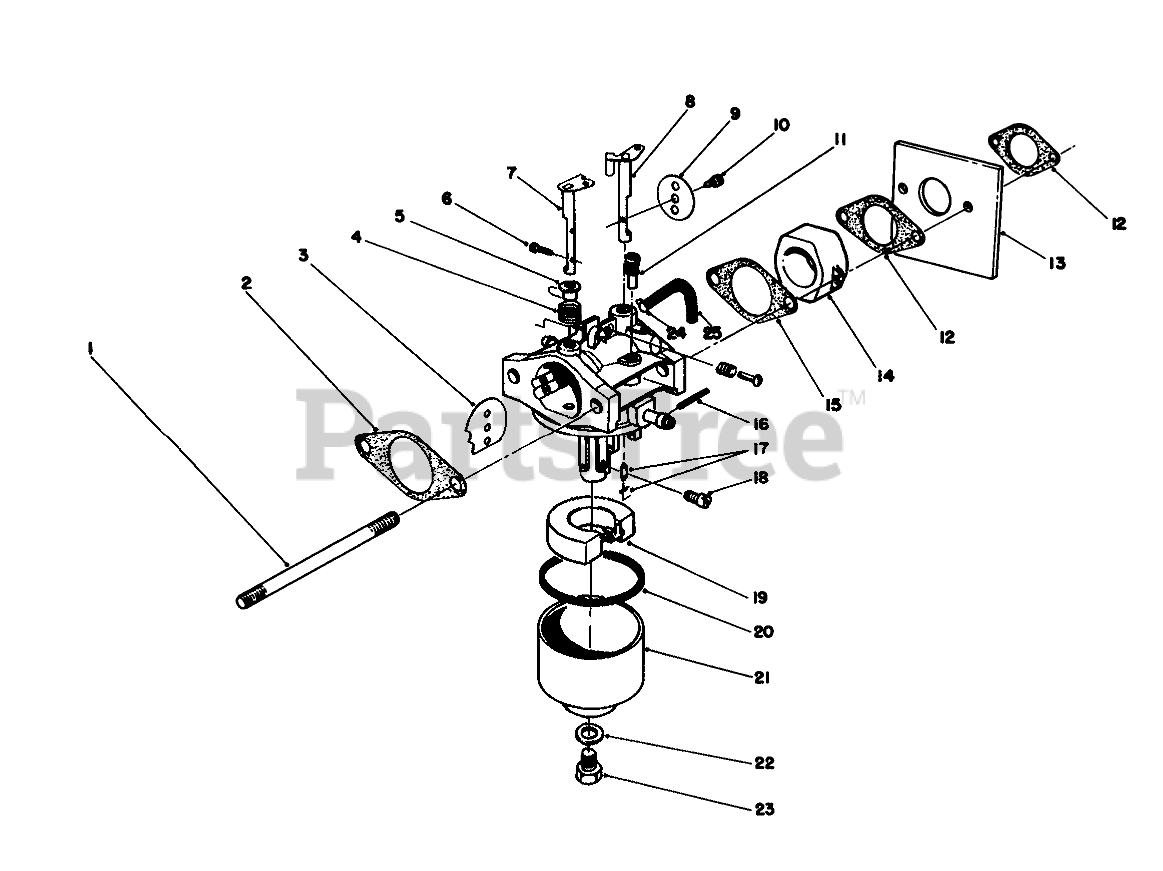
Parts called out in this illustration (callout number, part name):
1	STUD-CARBURETOR
2	GASKET-AIR CLEANER
3	AIR CLEANER
4	Spring-Choke
5	BUSHING
6	SCREW
7	SHAFT-CHOKE
8	GASKET F/W ENGINE
9	PLATE
10	Screw-Throttle
11	PILOT JET
12	GASKET
13	SHIELD-CARBURETOR
14	INSULATOR-CARBURETOR
15	Clamp
17	NEEDLE
18	JET-MAIN
19	FLOAT
20	GASKET
21	Bowl-Float
22	GASKET
23	Bolt
24	CLAMP
25	VENT TUBE
